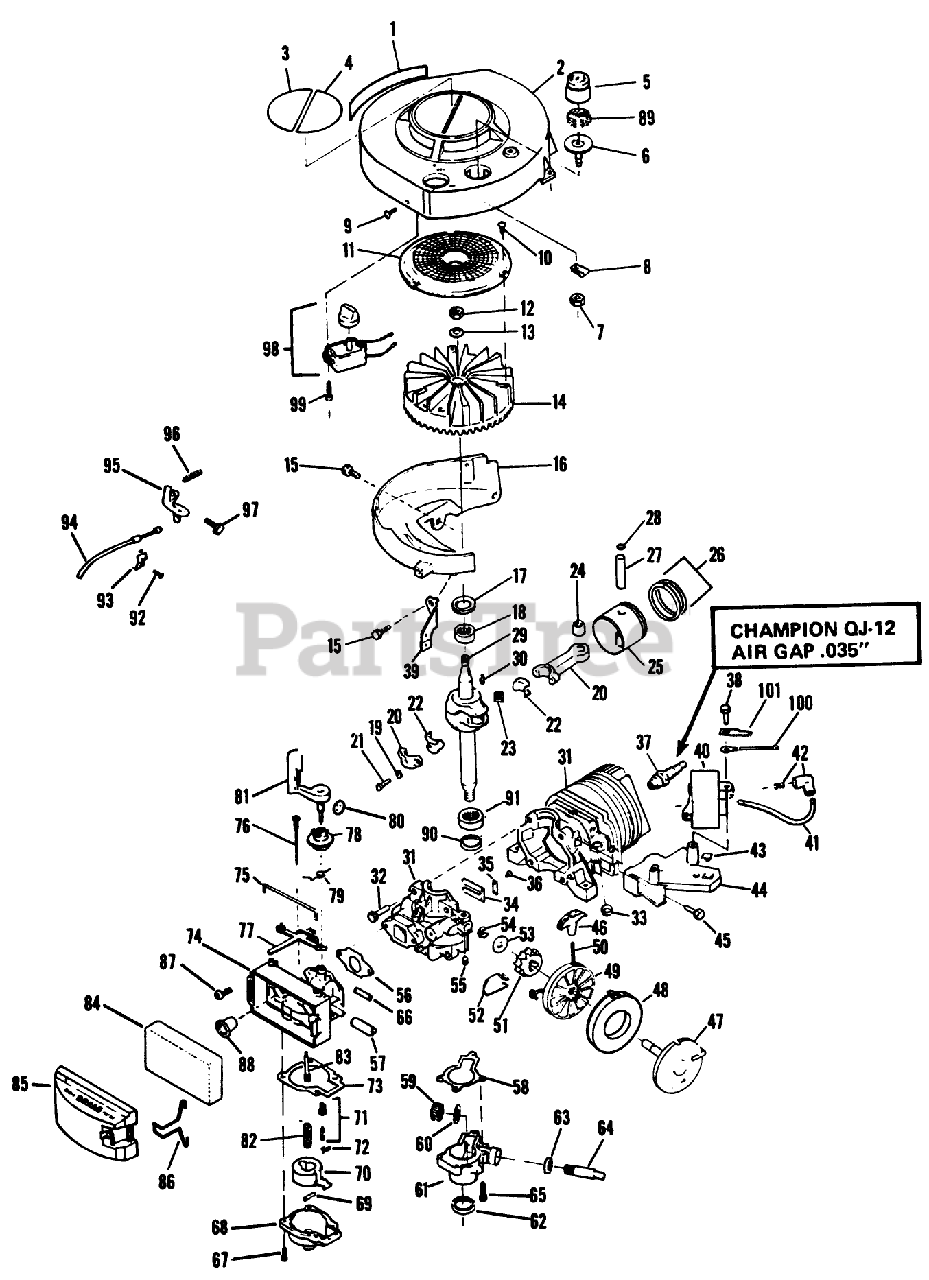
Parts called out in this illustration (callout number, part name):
3	Decal-Fuel
4	Decal-Start
7	LOCKNUT S
9	SCREW F
10	SCREW F
12	NUT
15	SCREW-SEMS
18	BEARING V
21	SCREW
21	SCREW-HSH
22	LINER ASM
24	BEARING AY F
28	RING-RETAINING
30	KEY
32	SCREW S
33	PLUG-CORE VF
35	PLATE-BACKUP, REED
41	HT LEAD&COVER XEV
43	NUT-CLIP
44	BRACKET S
46	HANDLE STARTER S
49	PULLEY STARTER S
52	SPRING F
53	WASHER S
56	GASKET CARB S
58	GASKET S
59	GEAR, DR SHAFT S
60	THRUST WASHER
62	SEAL-OIL
63	SEAL S
66	TUBING PRIMER S
67	SCREW-HH
74	CARB BODY S
75	RETAINER
76	NEEDLE ADJ. AY S
77	LEVER S
78	COLLAR-ADJUST, AIRVANE
79	SPRING,THROTTLE S
80	DISC S
81	AIR VANE&SHAFT S
82	FILTER-FUEL VS
86	RETAINER-COVER, FILTER
87	SCREW S
89	FILTER S
90	SEAL-OIL
91	BEARING S
93	CLIP S
95	LEVER LOCKOUT S
97	BOLT S
101	TERMINAL S
